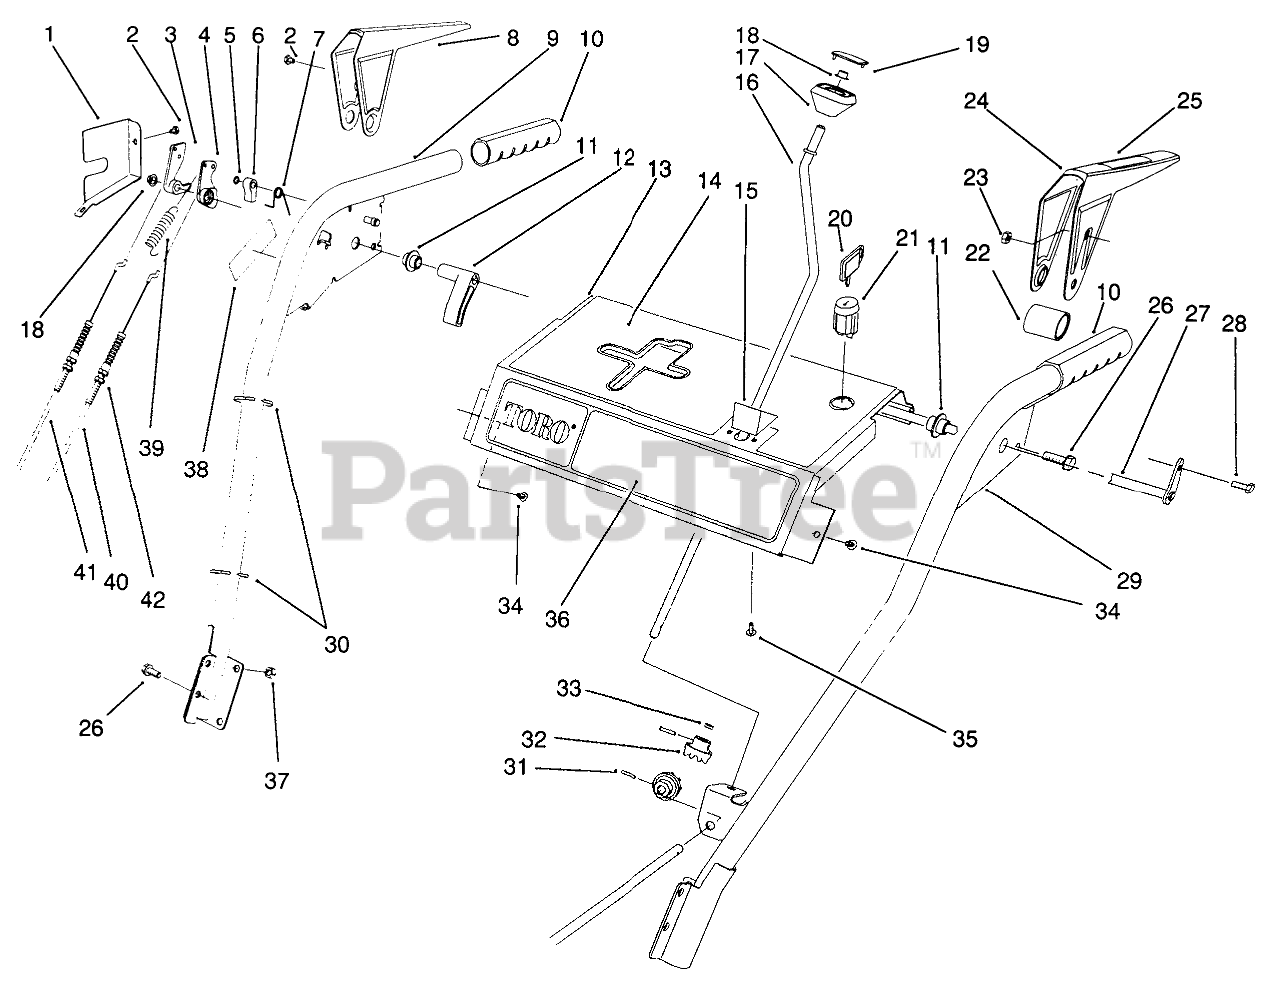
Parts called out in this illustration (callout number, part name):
1	Cover Lever Lock
2	SCREW-HH
3	TANG-LOCKING
4	CAM-RELEASE
5	E-RING-RETAINER
6	LATCH-LOCKING
7	SPRING-TORSION
8	Lever-Impeller
9	Handle-R.H.
10	GRIP-HANDLE
11	BUSHING-LEVER
12	LEVER-TRIP
13	Panel-Control
14	DECAL-TOP PANEL
15	PLATE-GUIDE
16	CRANK-ROD, CHUTE
17	KNOB-CONTROL, CHUTE
18	RETAINER-PUSH ON
19	COVER-KNOB
20	KEY-IGNITION
21	SWITCH
22	SPACER-LEVER, TRACTION
23	NUT-LOCK, NI
24	Lever-Traction
25	DECAL-LEVER
26	SCREW-HHF
27	CROSS ROD ASM
28	SCREW-HWH
29	Handle-L.H.
30	TIE-CABLE
31	PIN-SPRING
32	GEAR-UNIVERSAL
33	WASHER-RUBBER
34	SCREW-HWHTF
35	SCREW-PPH
36	DECAL-FRONT PANEL (828)
37	NUT-LOCK, NI
38	DECAL-WARNING
39	Spring-Extension
40	CABLE-TRACTION
41	CABLE-IMPELLER
42	NUT-LOCK, NI
